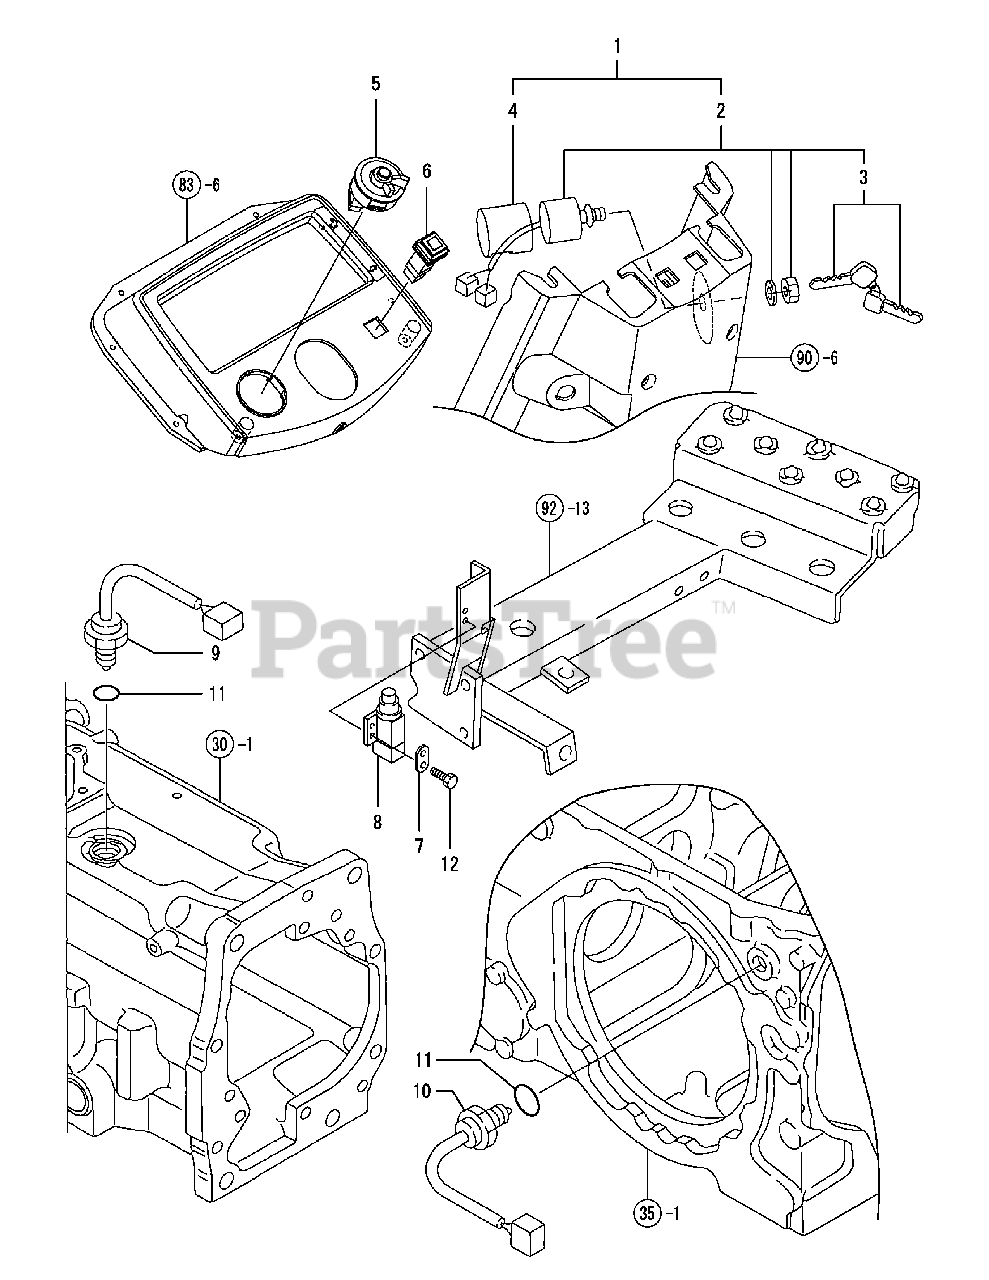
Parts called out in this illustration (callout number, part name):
2	SWITCH ASSY, STARTER
4	COVER,START SW
5	COMBINATION SW
8	STOP LAMP SW,DELTA
9	SWITCH, SAFETY START
10	SWITCH, SAFETY START
11	O-RING 1A P-18.0
